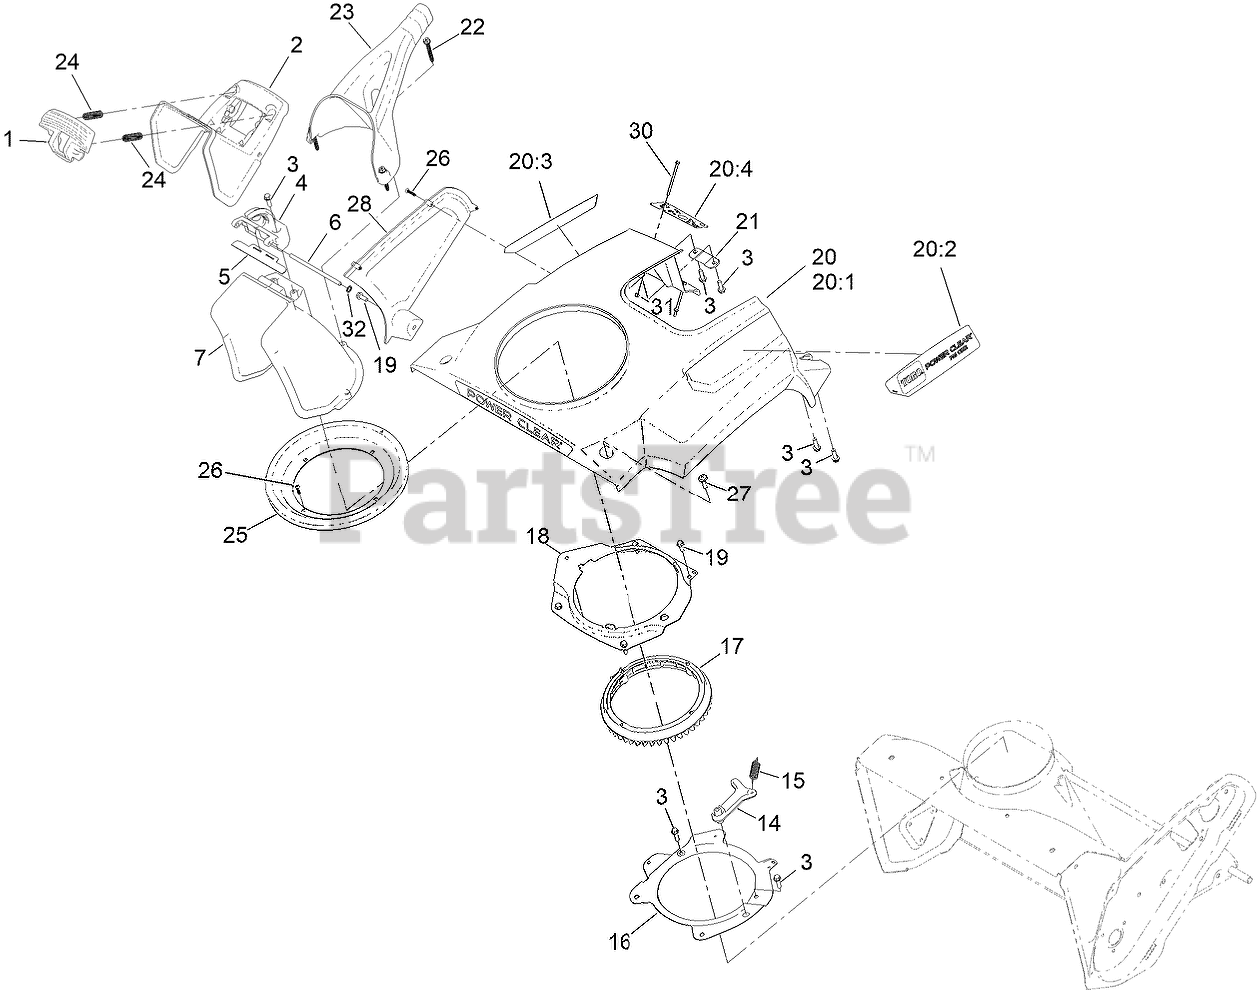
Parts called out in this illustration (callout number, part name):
1	TRIGGER-DEFLECTOR
2	DEFLECTOR-CHUTE, CE
3	SCREW-HWH
4	HINGE-RATCHET, DEFLECTOR
5	SEAL-DEFLECTOR
6	HINGE PIN-DEFLECTOR
14	PAWL-DETENT
15	SPRING-EXTENSION
16	RING-SUPPORT, CHUTE
17	RING-CHUTE, DETENT
18	RETAINER-RING, CHUTE
19	SCREW-HWH
20	SHROUD ASM, W/DECALS
20:1	SHROUD ASM, W/ARTWORK
20:2	DECAL-SHROUD LH
20:3	DECAL-SHROUD RH
20:4	DECAL-ENGINE, ELECTRIC START
21	RETAINER-SHROUD
22	SCREW-HWH, PLASTITE
23	HANDLE-CHUTE
24	SPRING-COMPRESSION
25	SEAL-RING, CHUTE
26	SCREW-PPH
27	SCREW-PPH
28	COVER-SIDE
30	SCREW-HWH
31	NUT-HEX
32	RING-RETAINING
